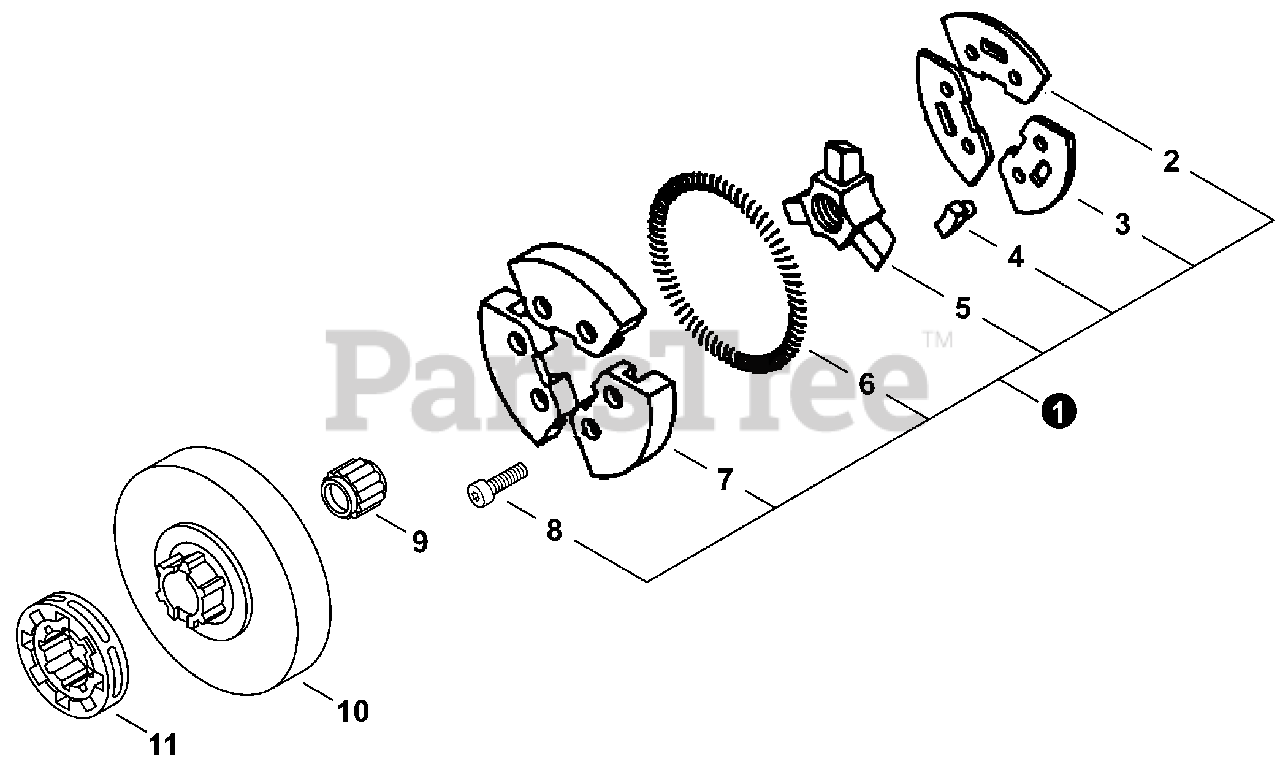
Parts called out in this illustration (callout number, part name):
1	CLUTCH ASSY
2	PLATE, CLUTCH
3	PLATE, CLUTCH
5	HUB, CLUTCH
6	SPRING, CLUTCH
7	CLUTCH SHOE SET
8	BOLT 4x8
9	BEARING, NEEDLE
10	DRUM, CLUTCH
11	SPROCKET, RIM 3/8"x7T
